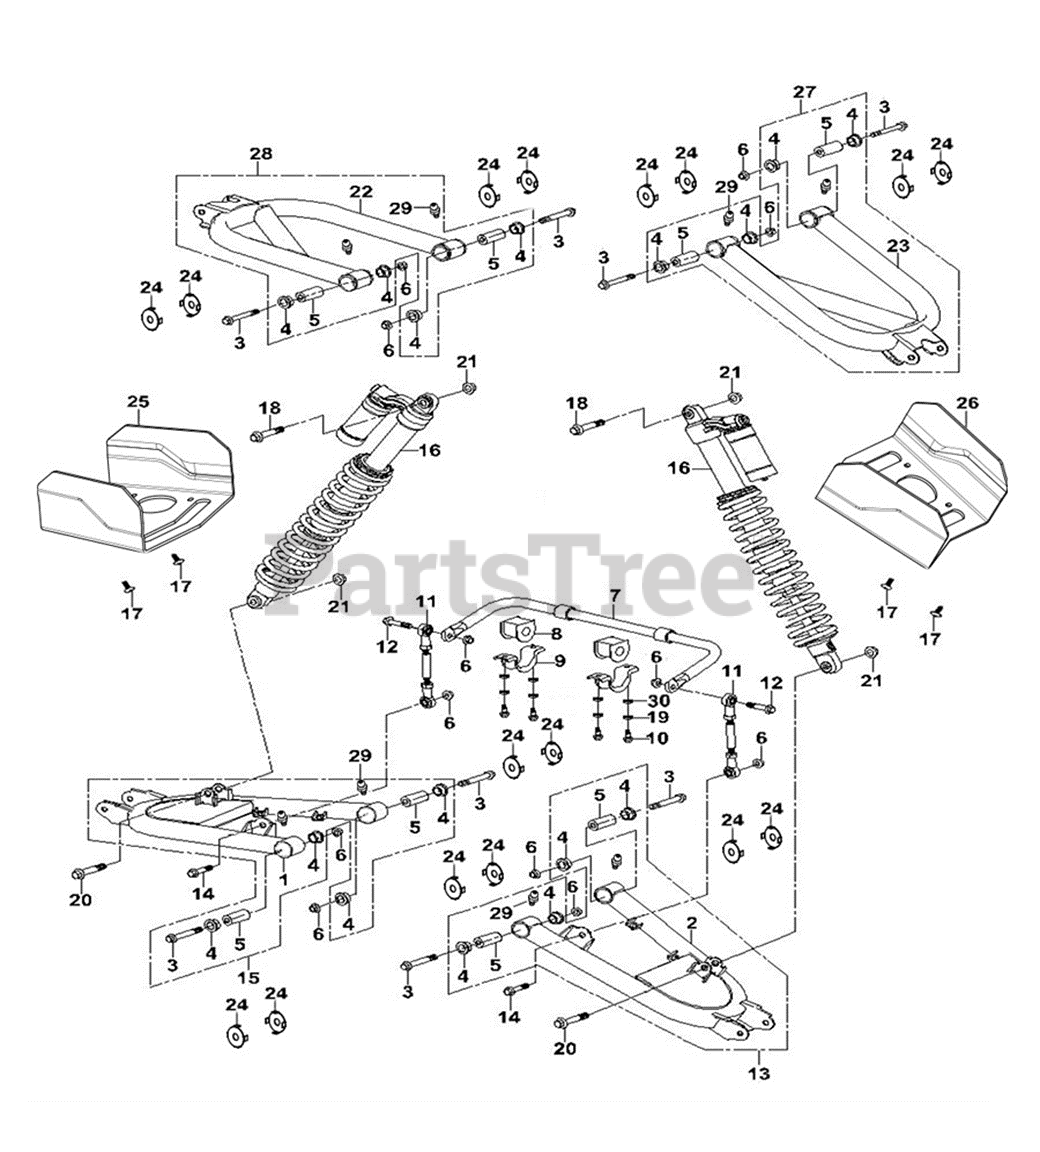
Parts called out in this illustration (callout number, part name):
1	Arm Welding Kit(Rear Right Lower)
2	Arm Welding Kit(Rear Left Lower)
3	HEX HEAD FLANGE BOLT M10X1.25-80
4	SHOULDER SPACER
5	BUSHING 10.3X23X49.4
6	LOCK NUT M10X1.25
7	STABILIZER BAR (REAR)
8	BUSHING - RUBBER U-TYPE
9	PRESS BLOCK REAR ANTI-ROLL BAR
10	HEX FLANGE BOLT M10X1.25X20
11	ROD BALL KIT - REAR
12	HEX FLANGE BOLT M10X1.25X50
13	Arm Assembly(Rear Left Lower)
14	HEX FLANGE BOLT M10X1.25X45
15	Arm Assembly(Rear Right Lower)
16	REAR SHOCK ABSORBER
17	SCREW M6X16
18	HEX HEAD BOLT M12X1.25-70
19	SPRING WASHER
20	HEX HEAD BOLT M12X1.25-65
21	LOCK NUT M12X1.25
22	Arm Welding Kit(Rear Right Upper)
23	Arm Welding Kit(Rear Left Upper)
24	BUSHING CAP I
25	SHIELD CV IV
26	SHIELD CV II
27	UPPER ARM ASSEMBLY (REAR LH )
28	UPPER ARM ASSEMBLY (REAR RH)
29	SWING ARM NOZZLE
